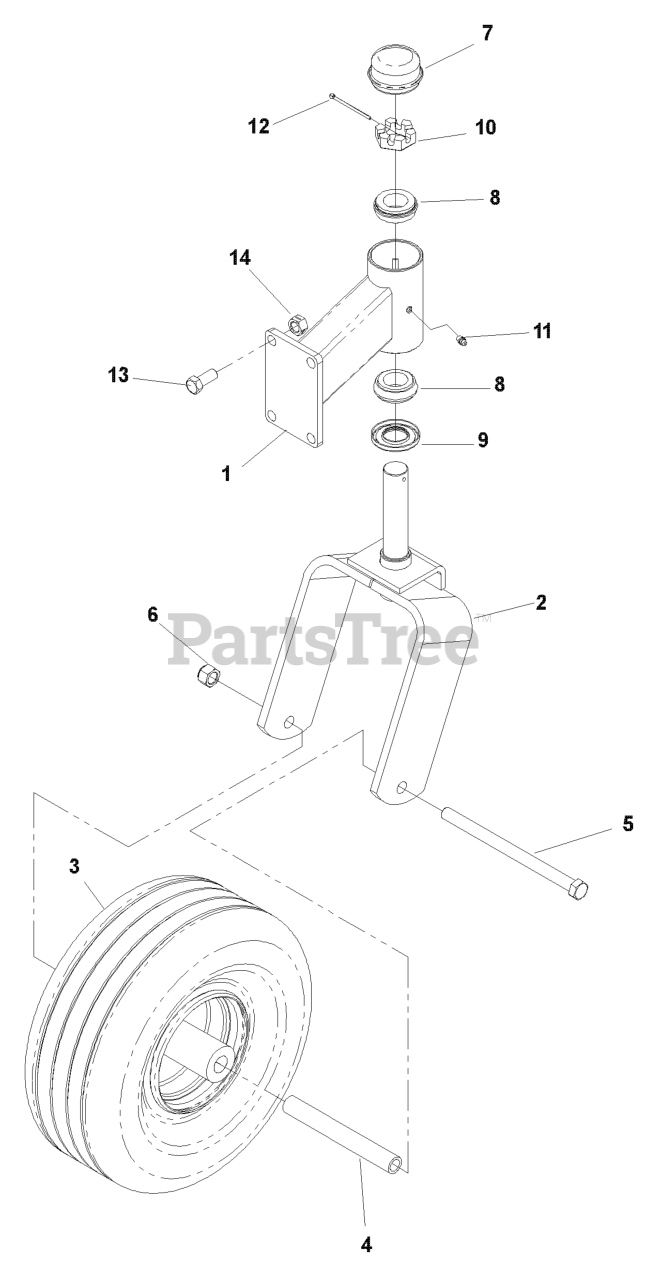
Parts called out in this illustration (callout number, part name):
1	CASTER ARM
1	CASTER ARM, ORG
2	CASTER YOKE ORANGE
3	TIRE.ASSEM.13X5-6.SMOOTH.SILVE
3	TIRE - FRONT
3	RIM
3	VALVE STEM TR-412
3	ZERK 1/8 NPT
3	BEARING RETAINER
4	SPACER, CASTER
5	SCREW 1/2C X 7 1/2 HEX CAP
6	NUT 1/2-13 HEX NYLOC ZD
7	GREASE CAP
8	TAPERED ROLLER BRG
10	NUT 1"C HEX SLOTTED
11	ZERK
12	COTTER PIN 1/8 X 2
13	HCS 7/16-14 X 1 GR 5 ZD
14	NUT 7/16C CENTERLOCK
